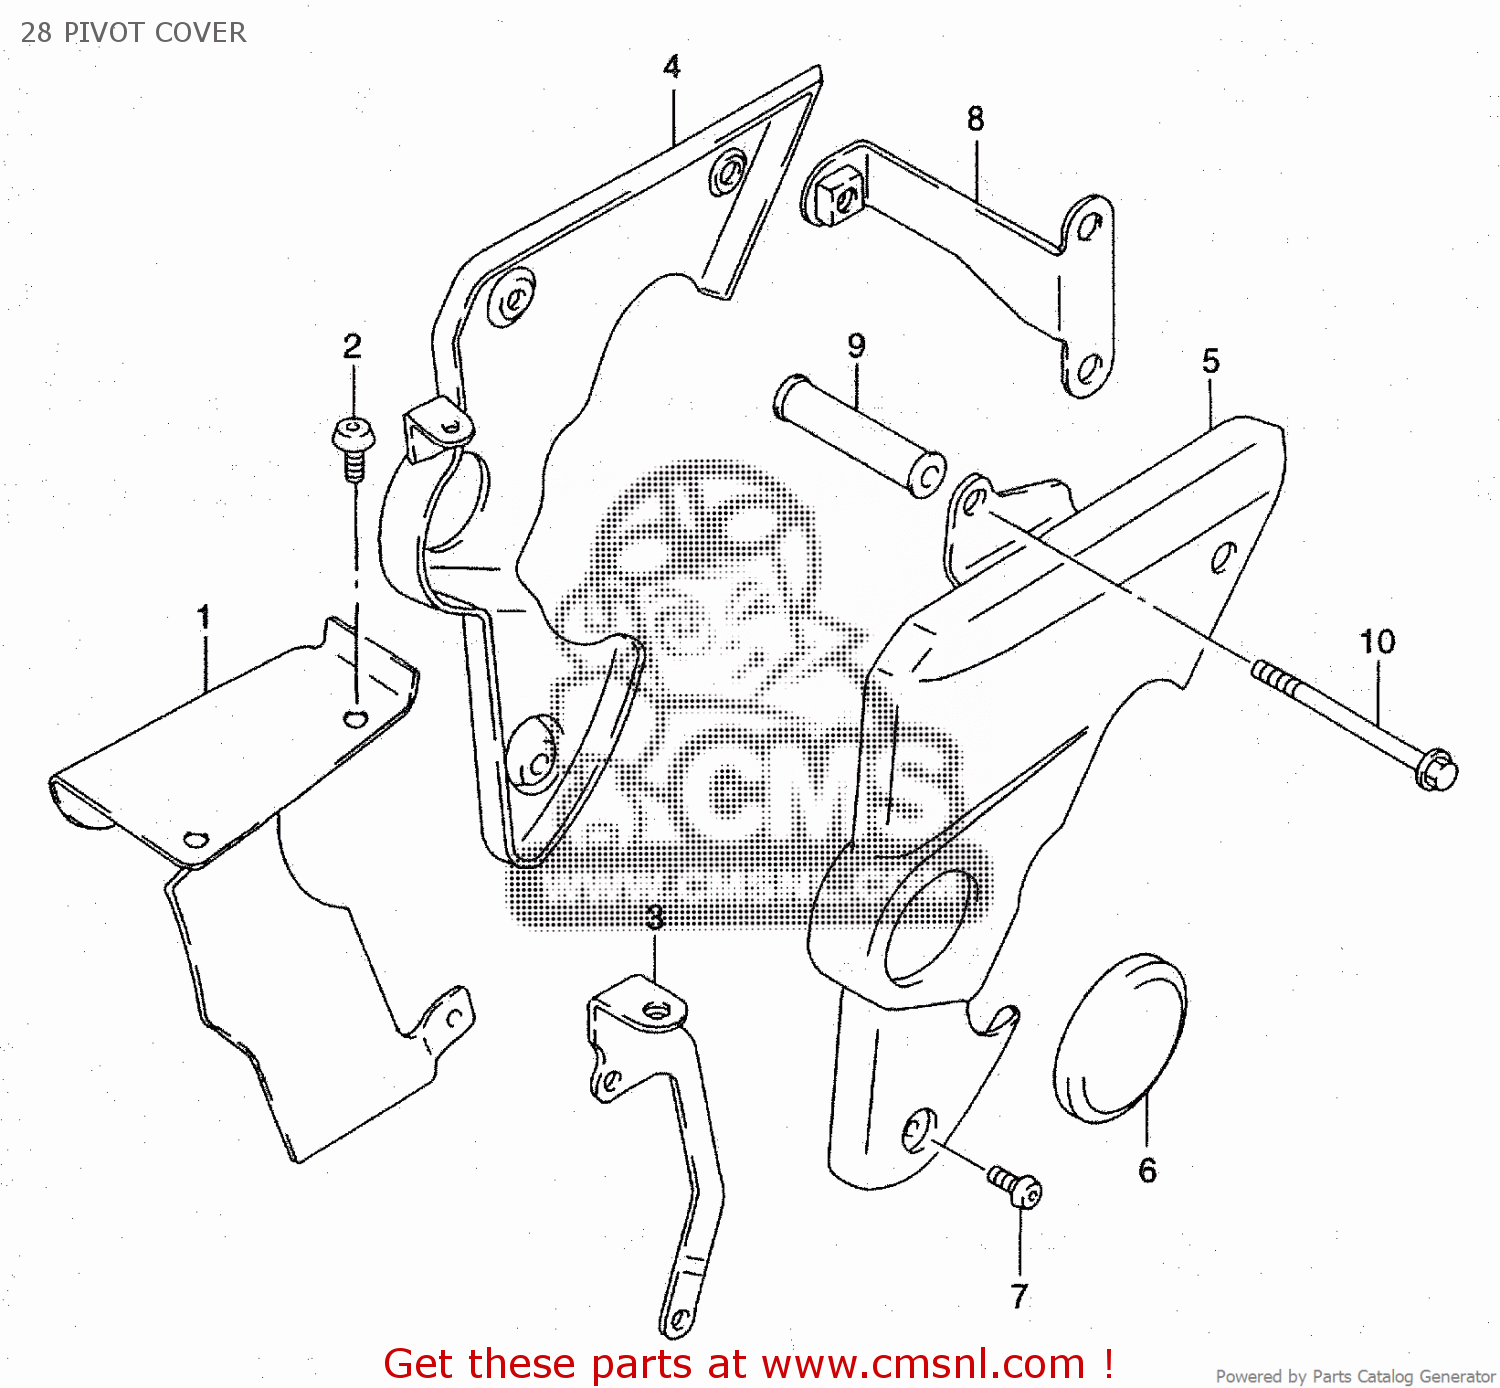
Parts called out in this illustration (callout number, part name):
2	SCREW(6X12)
6	CAP,FRAME BODY
7	SCREW(6X12)
10	BOLT
